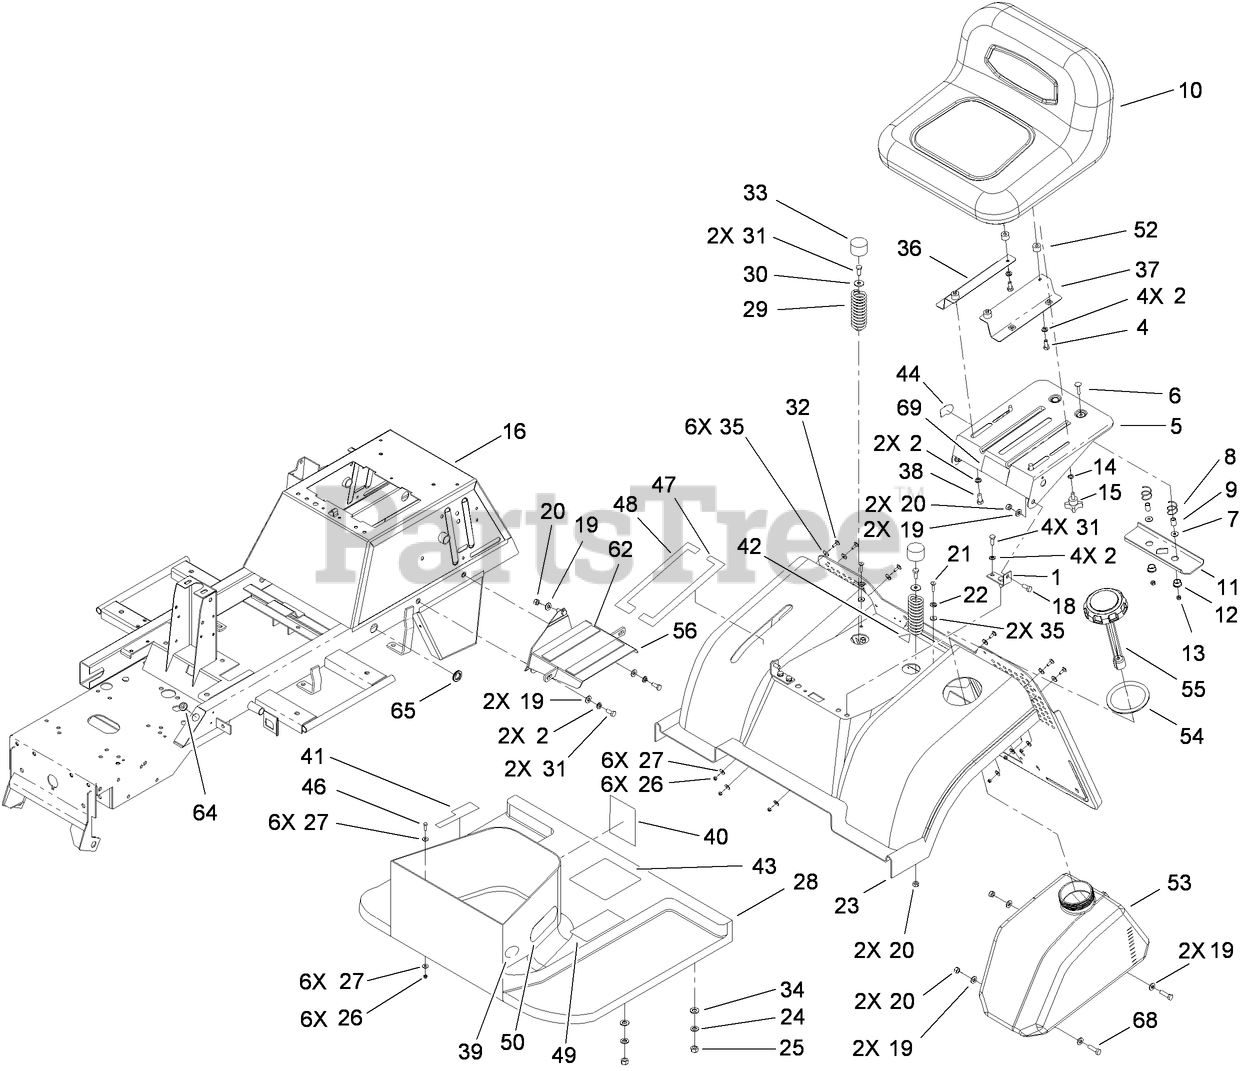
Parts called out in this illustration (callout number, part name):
1	BRACKET-SUPPORT, SEAT
2	WASHER-LOCK
4	SCREW-HH
5	SUPPORT-SEAT
6	BOLT-CARRIAGE
7	WASHER-FLAT
8	SPRING-SEAT
9	SPACER-SPLIT
10	SEAT ASM
11	BRACKET
12	BUSHING
13	NUT-LOCK
14	WASHER-SPRING
15	KNOB-ADJUSTMENT
16	CHASSIS-FRAME
18	SCREW-SUPPORT, SEAT
19	WASHER-PLAIN
20	NUT-LOCK, NI
21	SCREW-HSFH
23	FENDER-BODY, REAR
24	WASHER-FLAT
25	NUT-LOCK, NI
26	NUT-LOCK
27	WASHER-FLAT
28	FOOTREST ASM
29	SPRING-SEAT
30	WASHER-PLAIN
31	SCREW-HH
32	BOLT-CARRIAGE
33	CAP-HUB
34	WASHER-RUBBER
35	WASHER-RUBBER
36	BRACKET-SEAT, RH
37	BRACKET-SEAT, LH
39	DECAL-BRAKE, PARKING
40	DECAL-STARTING
41	DECAL-OPERATION, HYDRO
42	DECAL-BAG TO FRAME
43	DECAL-DANGER
44	DECAL-SWITCH
46	SCREW-HH
47	DECAL-HOC, LH
48	DECAL-HOC, RH
49	DECAL-OPERATION
50	DECAL-TOWER
52	SHIM-SEAT
53	TANK-FUEL
54	PROTECTOR-NECK, FILLER
55	CAP-FUEL
56	BRACKET-FUEL, TANK
62	STRIP-RUBBER, FUEL TANK
64	GROMMET
65	GROMMET
68	SCREW-HH
69	DECAL-DANGER
